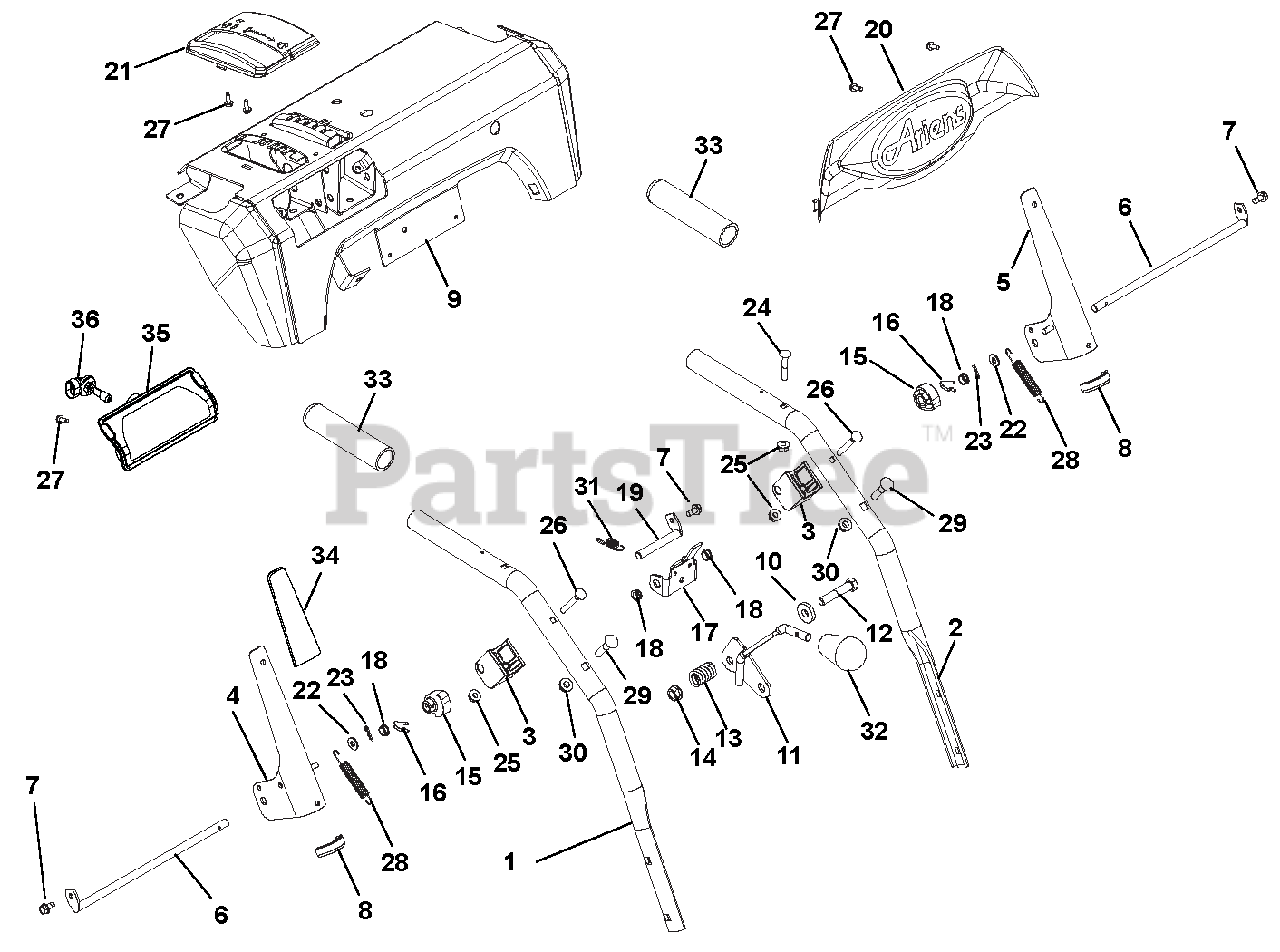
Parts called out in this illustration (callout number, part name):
1	HANDLEBAR, UPPER - RH
2	HANDLEBAR, UPPER - LH
3	BLOCK, CLUTCH PADDLE
4	LEVER, CLUTCH-RH
5	LEVER, CLUTCH-LH
6	ROD, PADDLE MOUNT - PRO
7	SCR-TAP .25-20X.50 HWH TR YWZ
8	EDGING, CLUTCH PADDLE - 2.00"
9	CONTROL PANEL W/DECAL
10	WSHR-FL-STL .406X1.00X.188 YWZ
11	WELDMENT, CONTROL LEVER(SHIFT)
12	@BLT-HEX .38-16X2.00 GR5 YWZC
13	SG-COMP .125X.781X1.250
14	@NUT-LK-TOP-FLG .38-16 YWZC
15	CAM, INTERLOCK
16	PIN, SPRING CLIP
17	BRACKET, INTERLOCK ARM
18	BUSHING, POLYLINER-.38 SNAPIN
19	ROD, PIVOT - INTERLOCK
20	DASH BEZEL, ARIENS LOGO - PRO
21	BEZEL, SHIFT ONLY
22	@WSHR-FL-STL.281X.62X.065 YWZC
23	PIN-HAIR INT .06X.18X.77
24	BLT-RDHDXLSQNK.25-20X1.25 G5ZC
25	@NUT-LK-TOP-FLG .25-20 YWZC
26	BLT-RDHDXLSQNK .25-20X2.0 G5YZ
27	SCR-TAP #10X.50 BOSS INDHXHD
28	SPRING, EXTENSION
29	@BLT-RDHDSQNK .31-18X1.50 G5YZ
30	@NUT-LK-TOP-FLG .31-18 YWZC
31	SPRING-EXT .047X.438X1.45
32	KNOB,SOFT TEARDROP,PUSH-ON GRY
33	HANDLE GRIP
34	CLUTCH PADDLE SLEEVE - GRAY
35	HEADLIGHT ASSY, HALOGEN 20W
36	BULB, LIGHT-HALOGEN 20W
